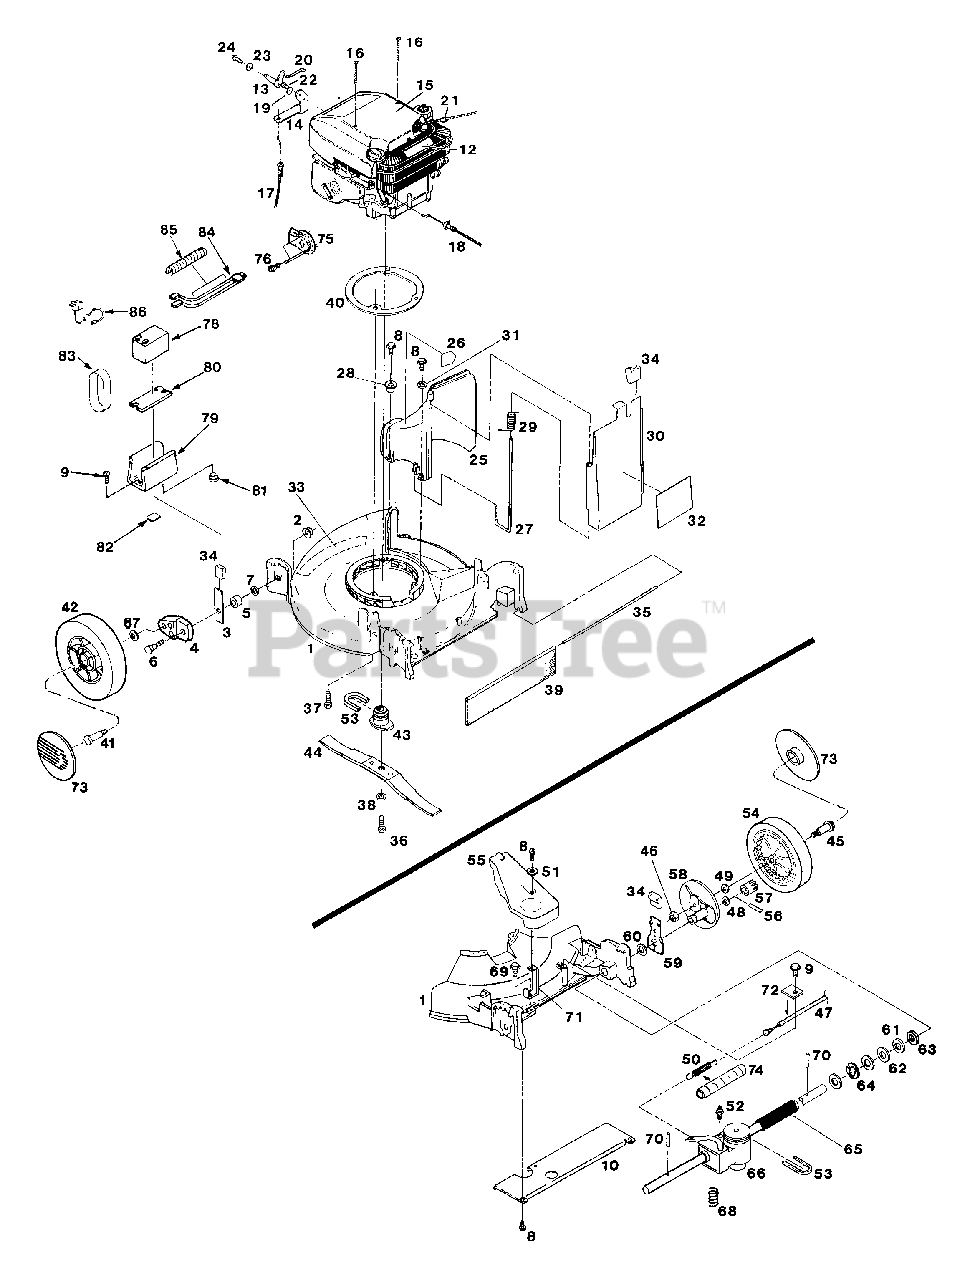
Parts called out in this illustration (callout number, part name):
1	DECK - 21" Propelled
2	NUT - 5/16" Flg. Lock
3	SETTING LEVER ASSY
4	ARM - Wheel mount
5	SPACER - WHEEL
6	BOLT - Height Adjuster
7	WASHER - 5/16" Flat
8	SCREW - 1/4-20 x 3/4" Hex Tap
9	SCREW - 1/4-20 x 5/8" Hex Tap
10	COVER - Rear
12	DECAL - Blade Warning BI/FR
13	BELLCRANK
14	BRACKET - Throttle
15	COVER ENGINE
16	SCREW - #8-32 x 1-1/4" Phil Tap
17	CONTROL - Throttle w/Cable
18	CABLE - Engine/Blade Control
19	SPACER - Stepped
20	LINK - throttle
21	ROPE STOP
22	SCREW - #10-24 x 3/8" Hex Tap
23	WASHER - 3/16" flat
24	SCREW - #10-24 x 3/4" Hex Tap
25	DISCHARGE CHUTE
26	DECAL - Chute
27	HINGE PIN
29	SPRING - Door Chute
30	DOOR - Chute
31	WASHER - 1/4" Flat
32	DECAL - Door Warning
33	DECAL - Logo 21"
34	PLASTIC TIP - Height Adjuster
35	ROD - Trailing Shield
36	BOLT - 3/8-24 x 1-1/4" HHCS GR8
37	BOLT - 3/8-16 x 2-1/4" Sems
38	WASHER - 3/8 Lock H.D.
39	TRAILING SHIELD - Plastic
40	ENGINE RING
41	BOLT - wheel
42	WHEEL - 8"
43	BLADE ADAPTER - 7/8" DIA. PP
44	BLADE - 21"
45	BOLT - wheel
46	NUT 3/8-16 Flg Lock
47	CABLE - Drive Control
48	WASHER - 5/8" x 22 GA. Hard
49	WASHER - 3/8" Flat
50	SPRING - Extension
51	WASHER - 1/4" Flat
52	VENT - Transmission
54	WHEEL - 8" w/gear
55	COVER - Drive
56	DRIVE PIN
57	PINION R.H.
58	DRIVE WHEEL SUPPORT Assy
59	SETTING LEVER - rear
60	SPACER - Rear adjuster
61	WASHER - 5/8" x 22 GA. Hard
62	WASHER - 5/8" x 14 GA. Flat
63	WASHER - 5/8" Wave
64	E-RING - 5/8"
65	COVER - Drive Shaft - 8 1/4"
66	TRANSMISSION - 1 spd
67	WASHER - Belleville
68	SPRING - Compression
69	SCREW - #10-16 Hex Tap
70	ROLL PIN - 1/8 x 7/8
71	BRACKET - Bell Cover
72	CLAMP - Drive Control Cable
74	WASHER - Thrust
75	DEFLECTOR - muffler
76	SCREW - #8-32 x 3/8
79	HOLDER - battery
80	PAD - battery rubber
82	SPACER - battery holder
83	BAND - rubber
84	LEAD - battery
85	Cover - harness
86	CHARGER - battery
